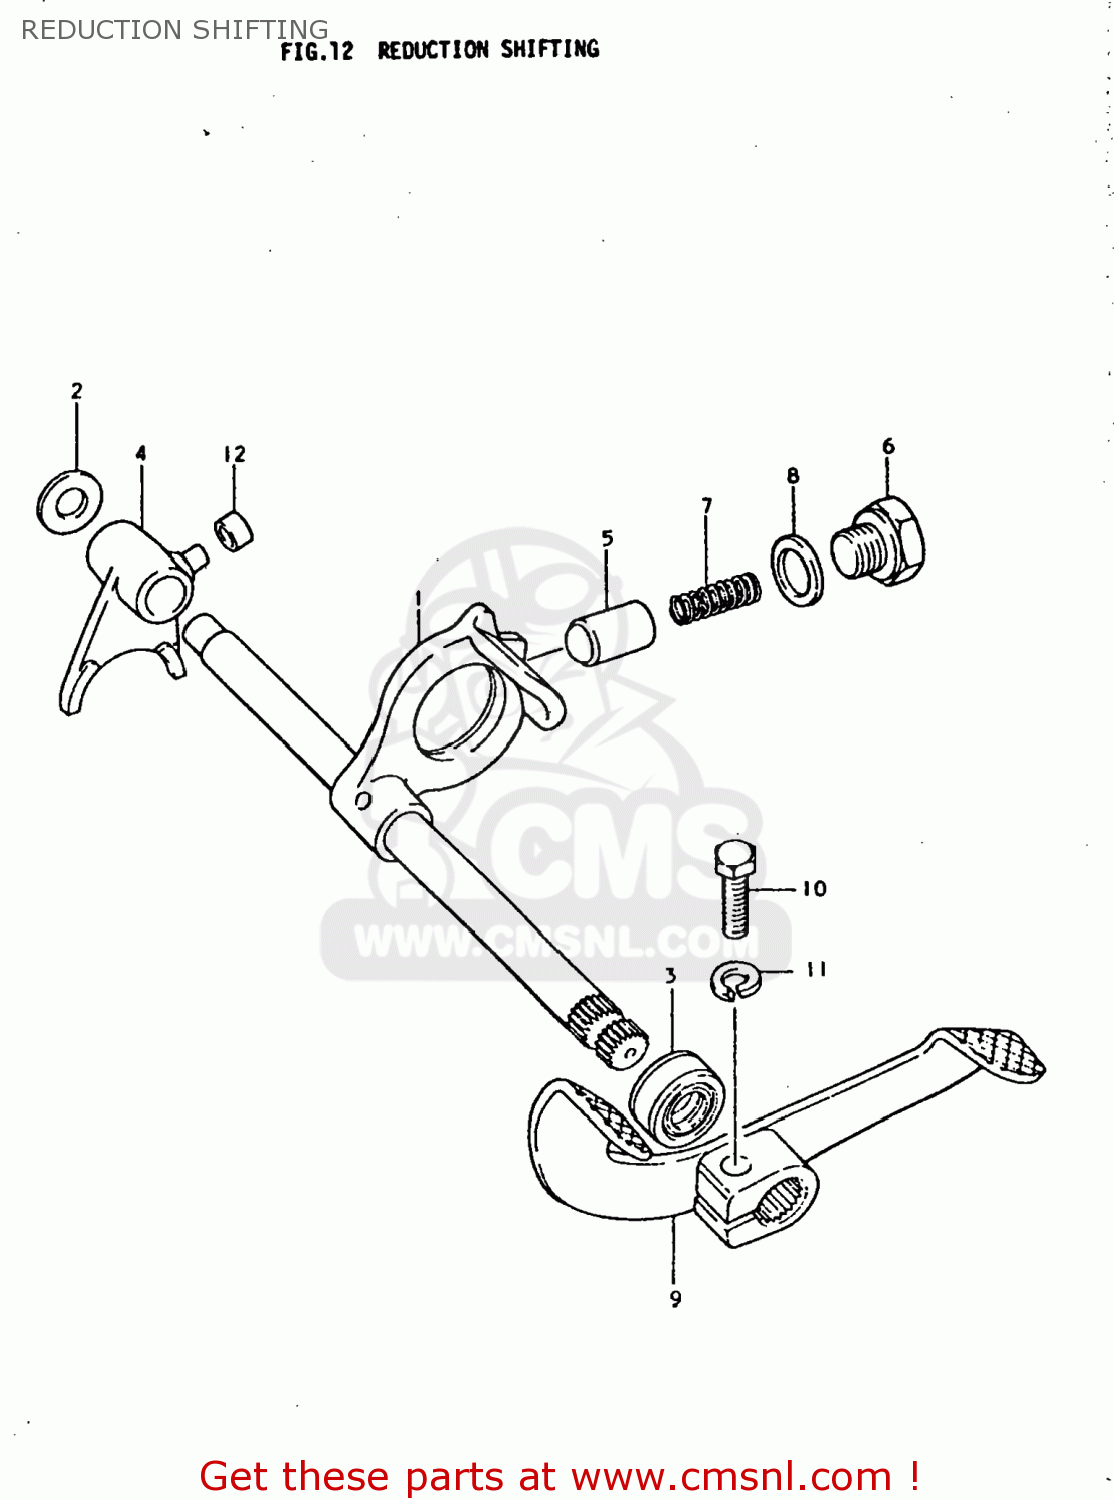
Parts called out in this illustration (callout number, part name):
1	SHAFT, REDUCTION SHIFTING AR
3	OIL SEAL
4	FORK,GEAR SHIFT NO.3
5	STOPPER,GEAR SHIFTING
6	PLUG
7	SPRING
8	GASKET(14X19.2X2) (NAS)
10	BOLT
11	LOCK WASHER
12	SPACER
